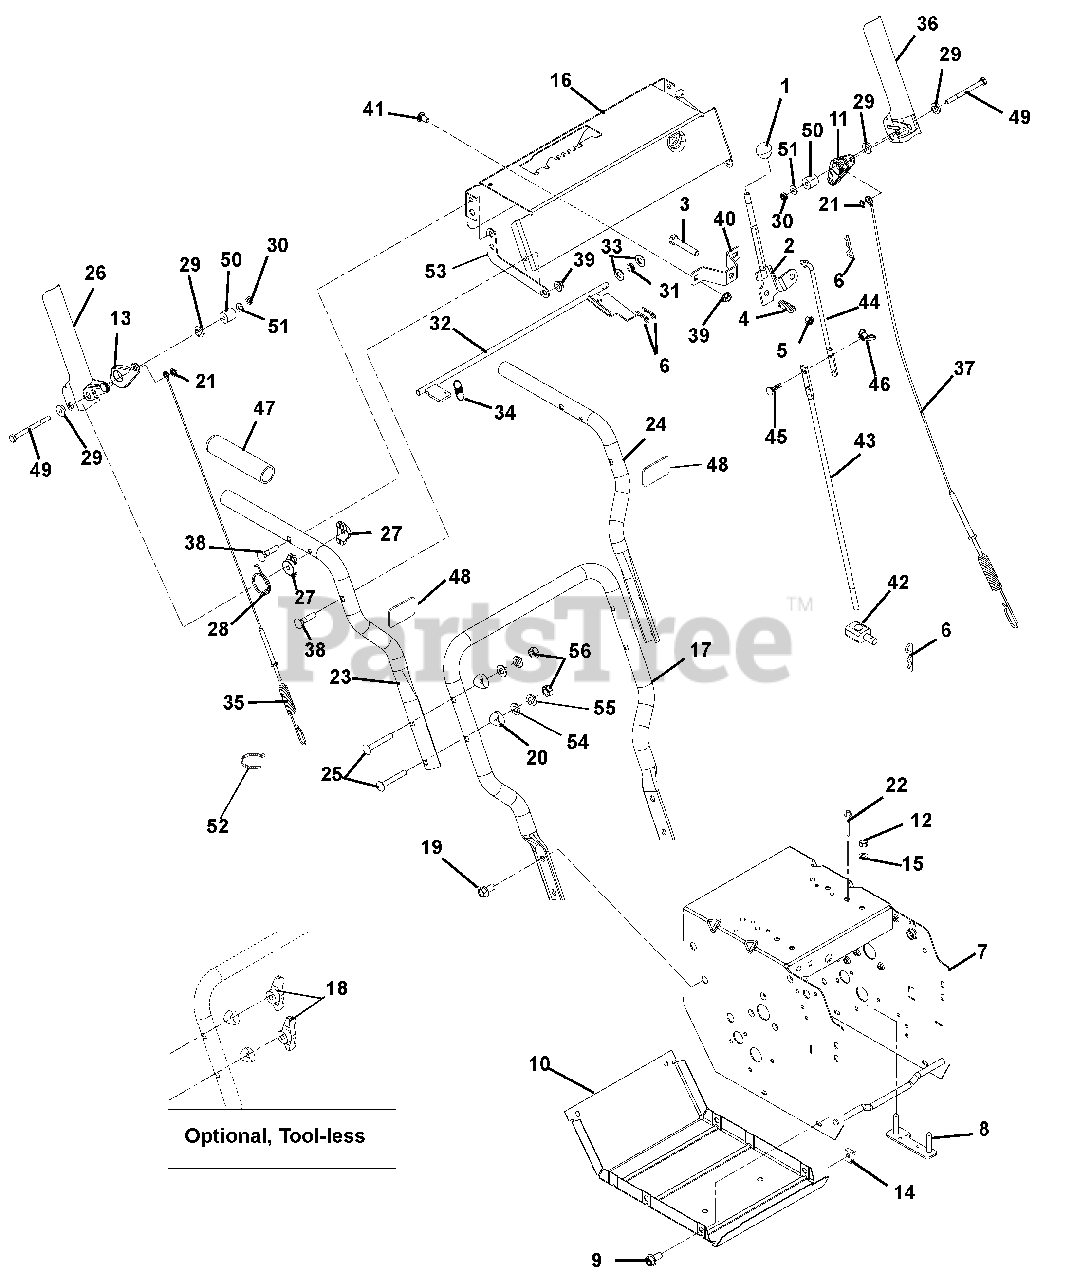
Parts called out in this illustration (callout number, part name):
1	KNOB,BALL -BLACK 1.47" .375-16
2	WMT, SHIFT LEVER
3	@BLT-HEX .38-16X2.00 GR5 YWZC
4	SG-COMP .125X.781X1.250
5	@NUT-LK-TOP-FLG .38-16 YWZC
6	PIN-HAIR INT .08X.18X1.18 YWZC
7	FRAME, MAIN
8	STRAP, ENGINE BOLT-WELDMENT
9	BLT-HEX .25-20X.75 HWH YZ GR5
10	COVER, BOTTOM
11	CAM, INTERLOCK - LH
12	@NUT-HEX .31-18 YWZC
13	CAM, INTERLOCK - RH
14	NUT-RTNR .25-20X.56
15	WSHR-LK .312X.097 HVY YWZC
16	CONTROL PANEL W/DECAL
17	HANDLEBAR, LOWER - DELUXE
18	KNOB - WING .312-18 UNC
19	BLT-SERHFWH .38-16X.75 YWZC
20	SPACER, HANDLEBAR
21	RG-RTNG-EXT .250X.010
22	RVT-POP .187 YZ
23	HANDLEBAR, UPPER - RH COMP/DEL
24	HANDLEBAR, UPPER - LH COMP/DEL
25	@BLT-RDHDSQNK .31-18X2.25 G5YZ
26	PADDLE, CLUTCH - RH COMPACT
27	SPACER, HANDLEBAR
28	SPRING, TORSION
29	BSHG, FLG .266X.42X.150 PM
30	NUT-JAM-NYL .250-20 W/INSERTYZ
31	BUSHING, POLYLINER-.38 SNAPIN
32	WELDMENT, INTERLOCK SHAFT
33	@WSHR-FL-STL.406X.812X.065 YWZ
34	SPRING, EXTENSION
35	CABLE, ATTACHMENT
36	PADDLE, CLUTCH - LH COMPACT
37	CABLE, TRACTION - DELUXE
38	BLT-RDHDXLSQNK .31-18X1.5 G5YZ
39	@NUT-LK-TOP-FLG .31-18 YWZC
40	BRACKET, SHIFT MOUNT
41	@BLT-RHDSSQNK .31-18X.62 G5YZ
42	PIVOT,SHIFT ROD .375-16(TRUNN)
43	ROD, SHIFT - LOWER
44	ROD, SHIFT - UPPER
45	@BLT-RDHDSQNK .25-20X.75 G5YZ
46	NUT-LK WING .250-20 YWZC
47	HANDLE GRIP
48	BUMPER PAD
49	@BLT-HEX .25-20X3.25 YWZC
50	BSHG, SLV .266 X .750 X .750
51	@WSHR-FL-STL.281X.62X.065 YWZC
52	CABLE TIE LG 5-1/2
53	STRAP, SUPPORT - DASH PANEL
54	@WSHR-FL-STL.38X.875X.083 YWZC
55	@WSHR-LK .31X.078 REG YWZC
56	@NUT-LK-NYL .312-18 YWZC
